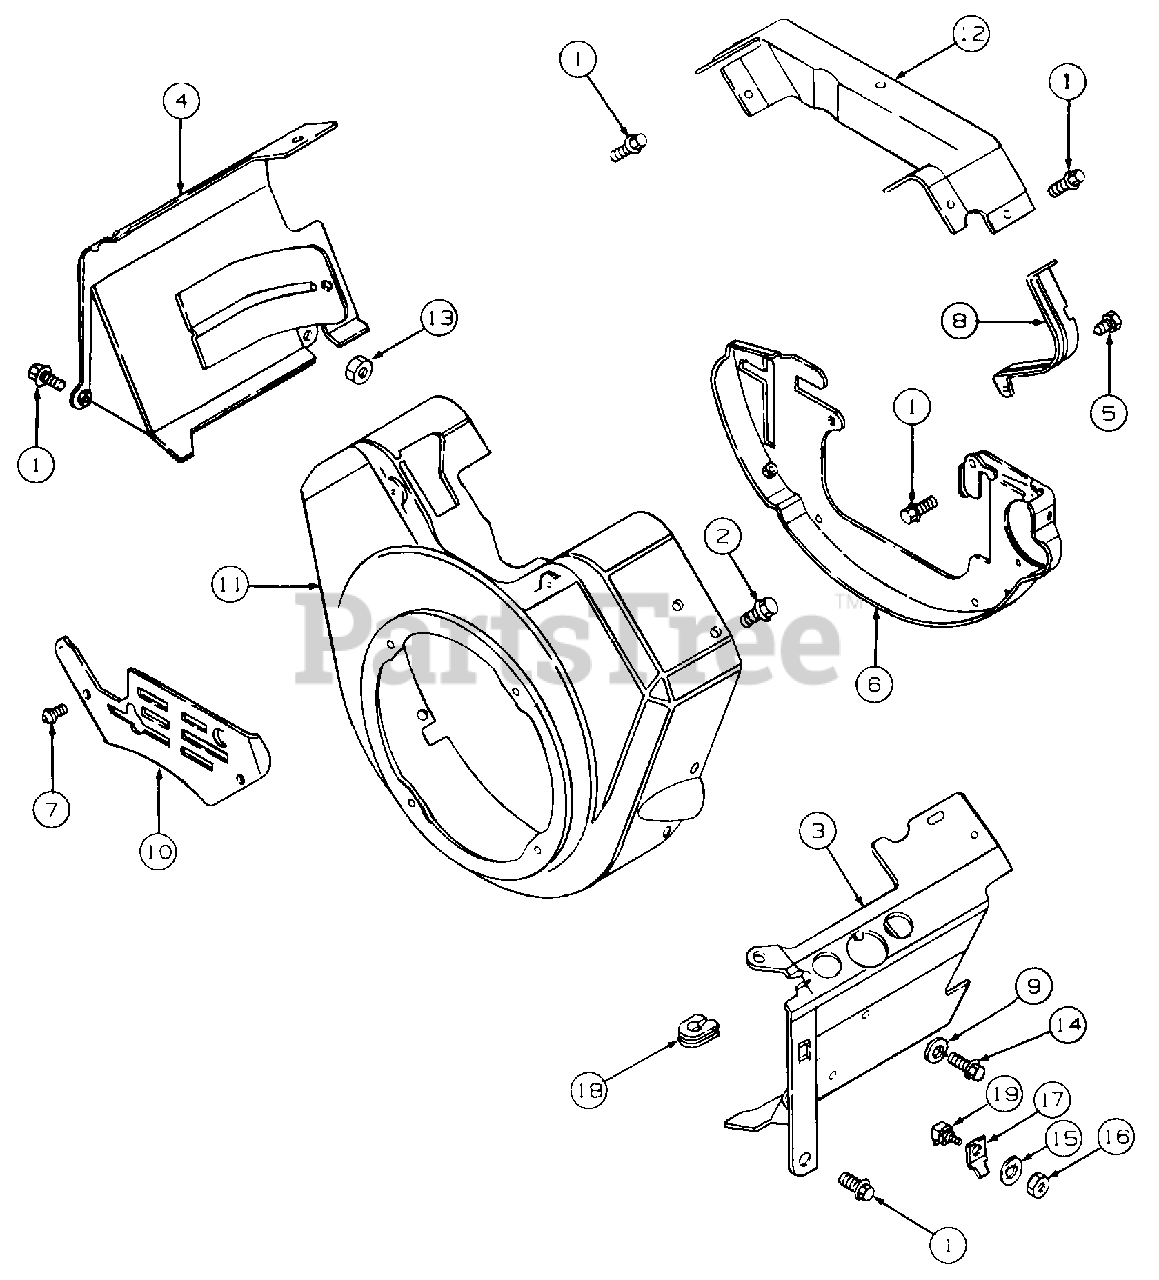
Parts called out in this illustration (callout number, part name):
1	Screw, Sems
2	Screw, Sems
3	Cover, Cylinder #1
4	Cover, Cylinder #2
5	Screw, Sems
6	Plate, Back
7	Screw, Sems
9	Washer, Lock
10	Cover, Carburetor
11	Housing, Blower
12	Cover, Valley Extension
13	Nut, Hex
14	Screw, Mtg.
15	Washer, Lock, Internal Tooth
17	Terminal, Ground
18	Grommet, Cable
19	Insulator Assembly
